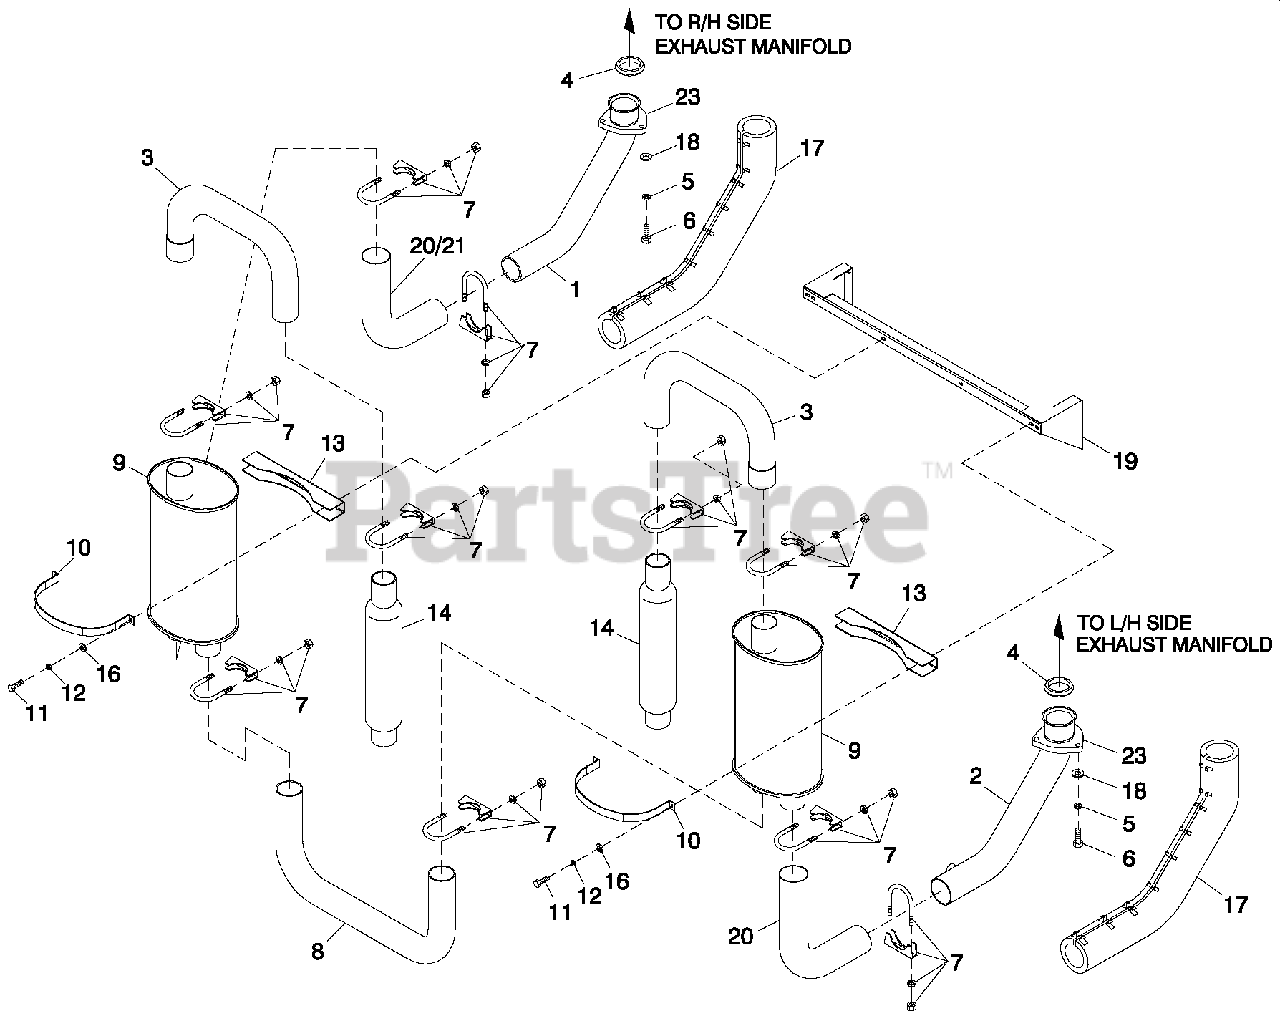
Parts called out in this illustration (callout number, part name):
1	PIPE, EXH MANIFOLD 6.8L C3 RH (6.8L 70KW)
2	PIPE EXH MANIFOLD 6.8L C3 LH (6.8L 70KW)
3	PIPE EXHA UST MUFFLERO UT
4	RING GASKET, 2.5DIA
5	WASHER LOCK M10SS
6	SCREW HHC M10-1.5 X 50 SS FTH
7	BOLT U 3/8-16X2.62
8	PIPE EXHA UST CROSSOVER
9	MFLR 7" X 9" X 25" (2) 2.5" IN/2.5" O UT
10	M U FFLER STRAP
11	SCREW HHC M6-1.0X 16 G8.8
12	WASHER LOCK M6-1/4
13	M U FFLER BRACKET STIFFENER
14	GLASS PACK 23.5" LG 2.5" IN/OUT
16	WASHER FLAT 1/4-M6 ZINC
17	EXHA UST BLANKET 800MM LG (6.8L 70KW)
18	WASHER FLAT 3/8 SS
19	BRKT M UFFLER
20	PIPE LH MUFFLER SIDE
21	PIPE RHM UFFLER SIDE
23	FLANGE, EXHAUST
